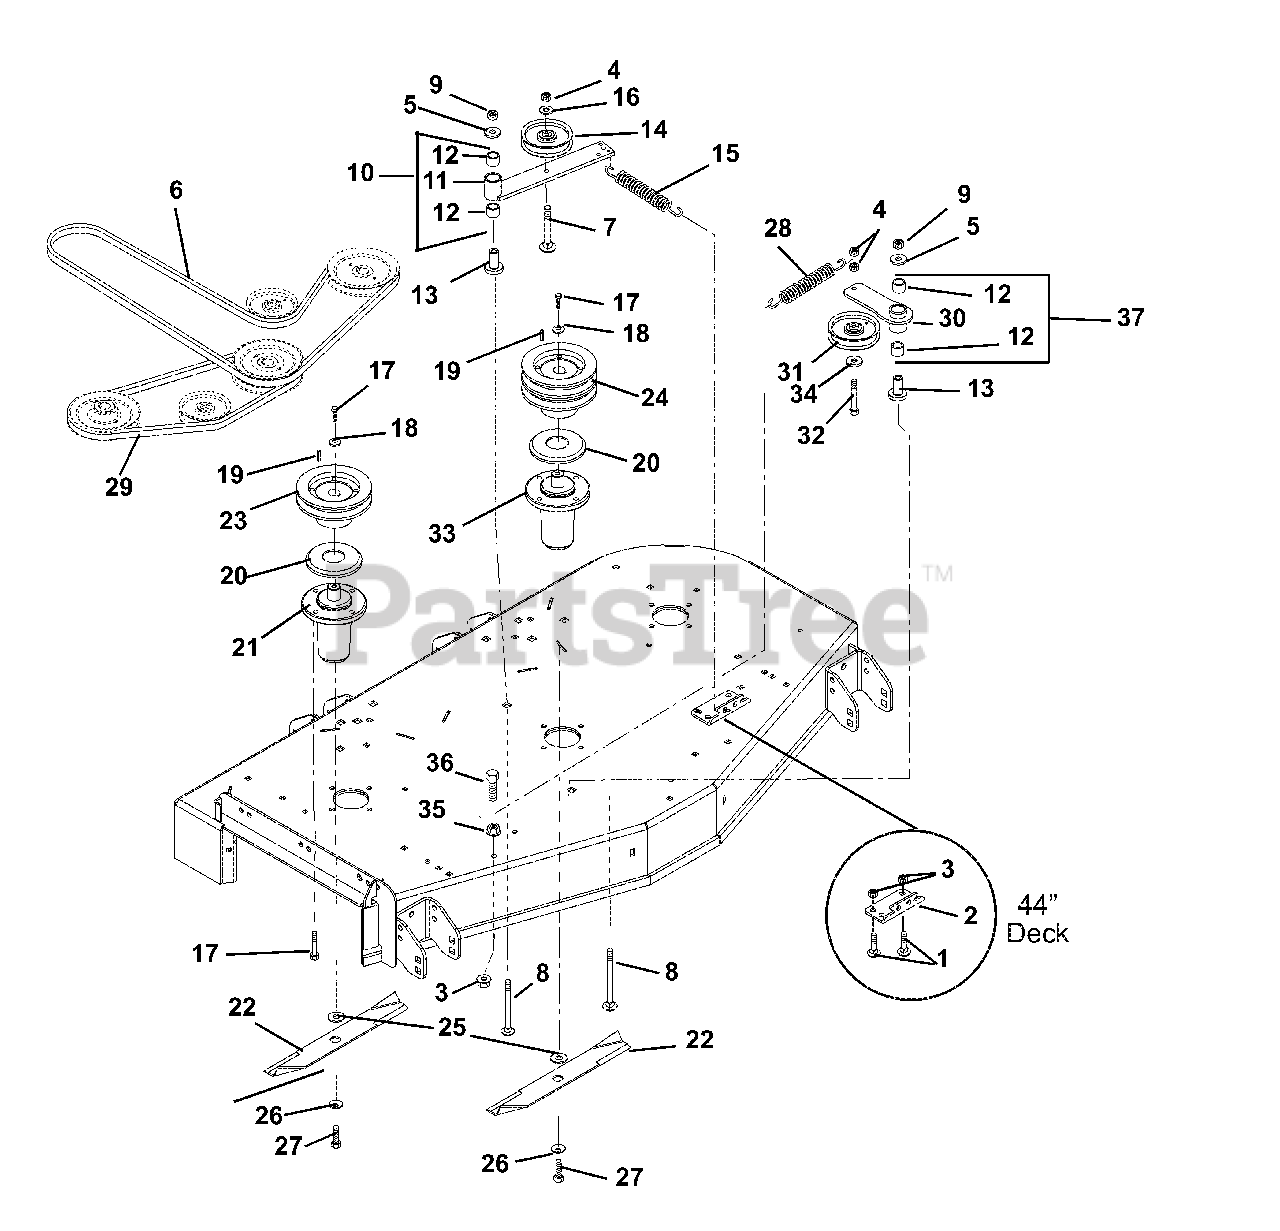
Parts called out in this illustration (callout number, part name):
1	@BLT-RDHDSQNK .38-16X.75 G5YZ
2	BRACKET, SPRING
3	@NUT-LK-TOP-FLG .38-16 YWZC
4	@NUT-LK-CTR .38-16 YWZC
5	WSHR-FL-STL .531X1.250X.10 YWZ
6	V-BELT, HB-WRAPPED
7	@BLT-RDHDSQNK .38-16X2.75 G5YZ
8	@BLT-RHDSSQNK .50-13X3.50 G5YZ
9	@NUT-LK-TOP-FLG .50-13 YWZC
10	ASSEMBLY - IDLER PIVOT ARM
11	WMT - IDLER PIVOT ARM
12	BRG, 1.00 X 1.12 X .75
13	BEARING, PEDESTAL
14	IDLER-FLAT 4.00X.38 (2.00 W)
15	SPRING, EXT0NSION DIA1.0X6.0LG
16	WSHR-FL-STL .375X1.125X.065YWZ
17	BLT-HEX .38-16X1.00 YZ GR8
18	WSHR,FLT STL.406X1.50X.245YWZC
19	KEY, SQ .25X.25X1.00 RC 40-50
20	SLINGER, DUST
21	ASM,MAINT FREE SPINDLE
22	BLADE, 32" (16.25)
22	BLADE - MULCHING (16.25)
23	WELDMENT, SPINDLE SHEAVE 5.00
24	SHEAVE, DOUBLE (5.25")
25	WSHR-FLT .640X1.75X.250 YWZC
26	WSHR-BLVL .669X1.535X.138
27	BLT-HEX .62-18X1.75 GR8 YWZC
28	SPRING, EXT
29	V-BELT, HB-COGGED
29	V-BELT, HB-RAW EDGE
30	WMT, IDLER PIVOT ARM
31	V-IDLER, 4.00X.38
32	@BLT-HEX .38-16X2.25 GR5 YWZC
33	ASM,MAINT FREE SPINDLE
34	@WSHR-FL-STL.406X.812X.065 YWZ
35	@NUT-SPNLK-FLG .375-16 YWZC
36	@BLT-HEX .38-16X3.50 GR5 YWZC
37	ASM, IDLER PIVOT ARM
